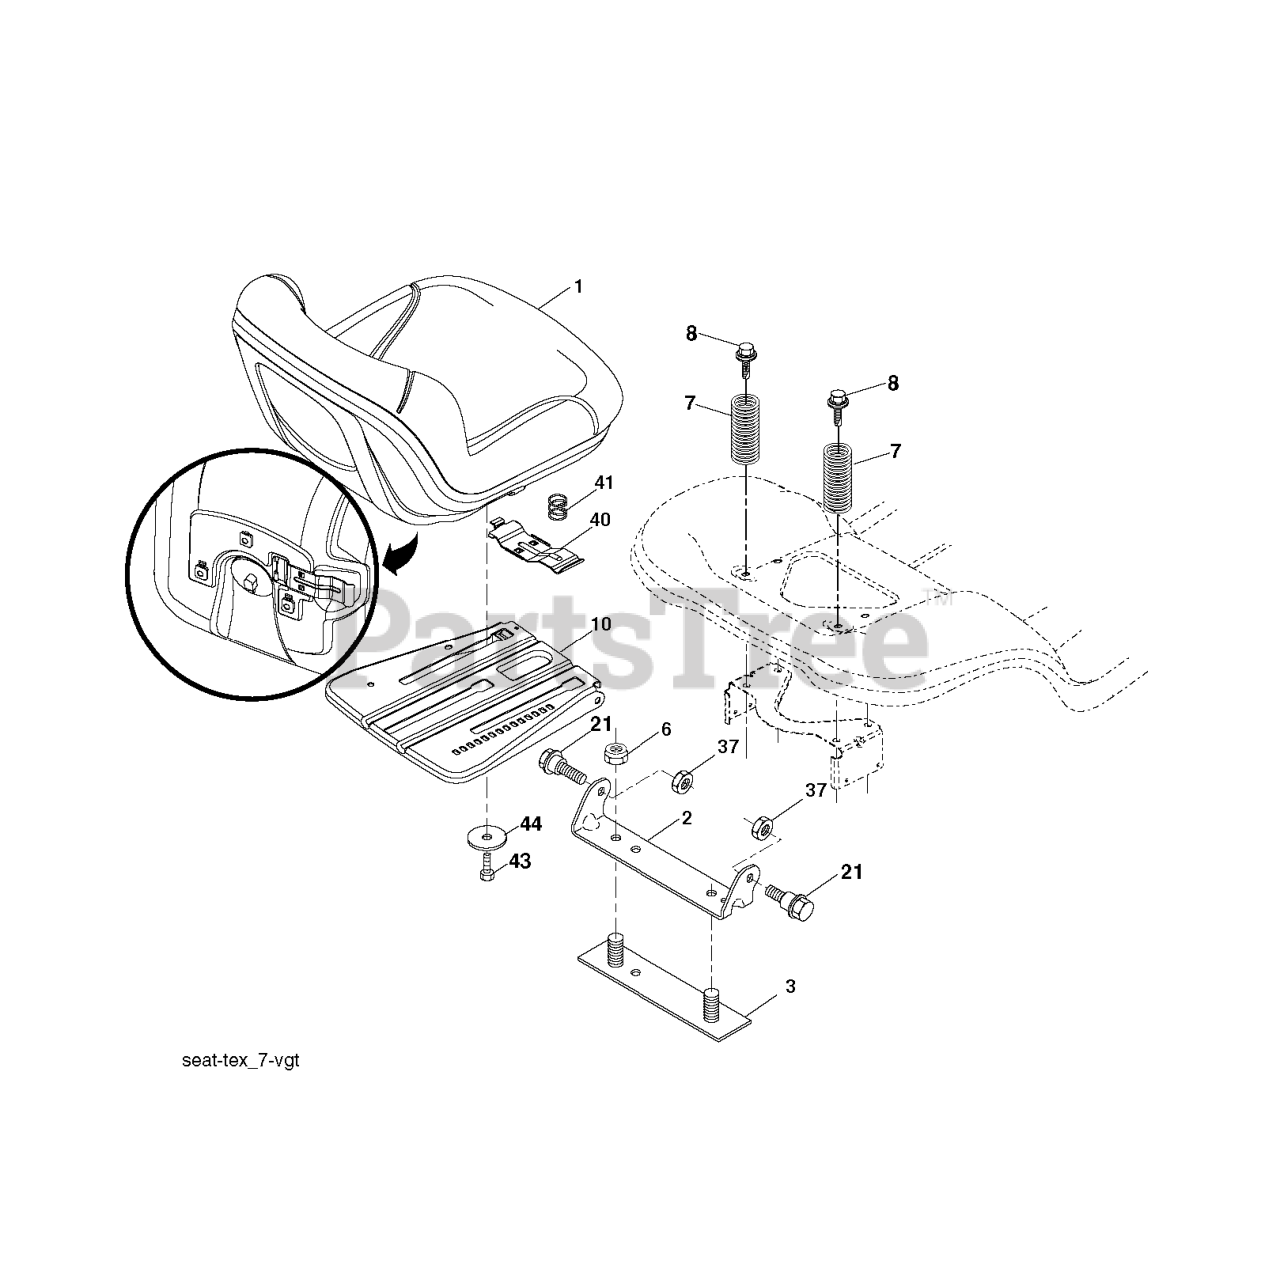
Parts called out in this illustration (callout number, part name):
1	SEAT.TH130.GRY.MILSCO.
2	BRKT.PIVOT.FENDER
3	STRAP
6	NUT
7	SPRING COMPRESSION
8	BOLT.5/16-18UNCX3/4 W/SEMS.BLK
10	PAN.ASM.SEAT.3PT
21	BOLT.SHOULDER.5/16-18
37	NUT.71038.31-18.HEX.NYLOCK
40	HANDLE.SLIDE.SEAT.TEX.BLACK
41	SPRING.LATCH.SEAT.TEX
44	WASHER 13/32 X 2-3/8 X 12GA
